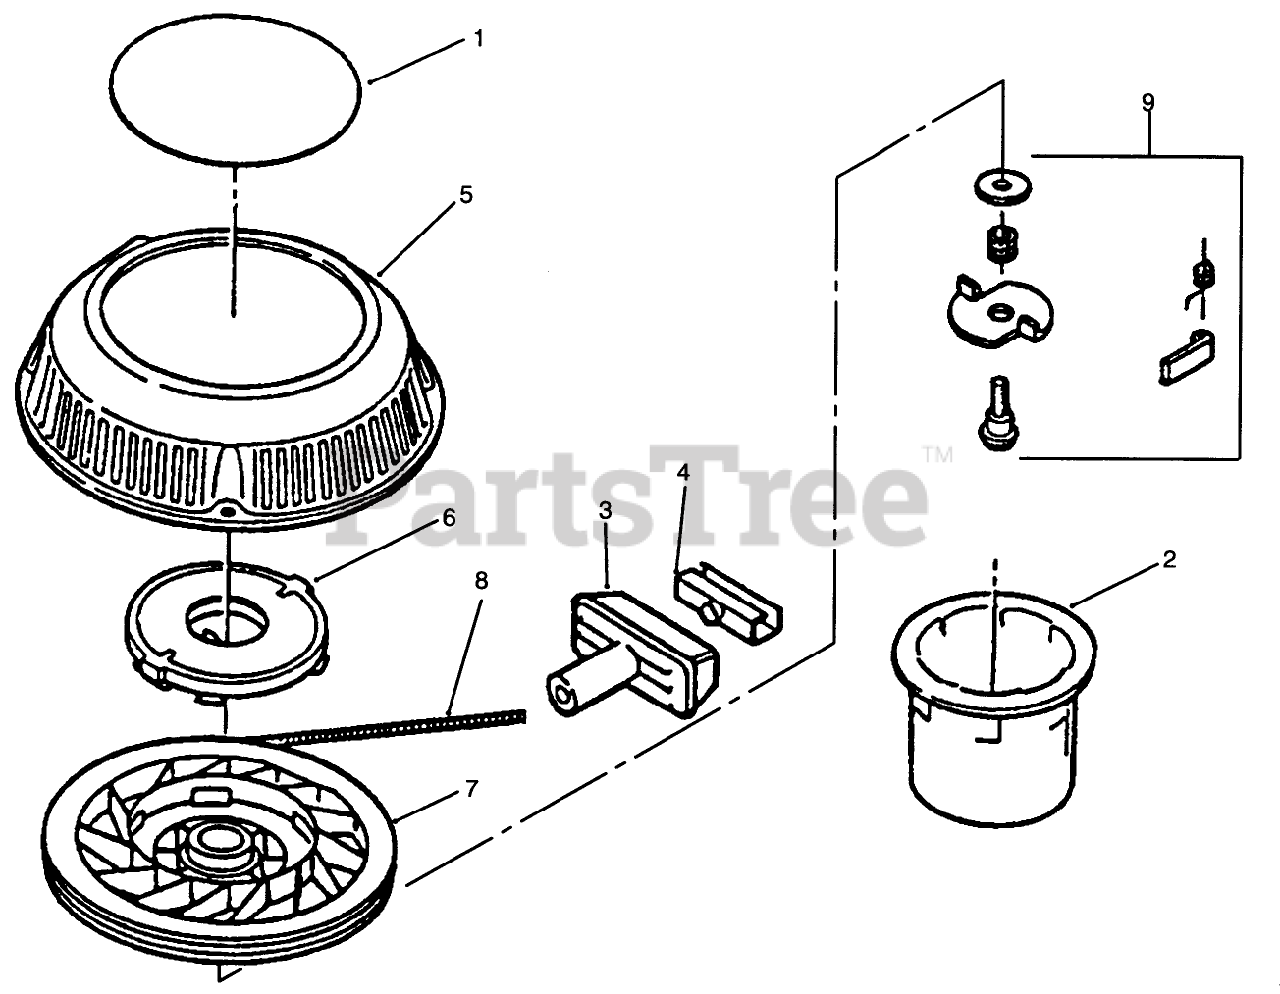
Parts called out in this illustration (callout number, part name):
2	HUB STARTER SM
4	CLIP-STARTER
5	STARTER HOUSING & SHAFT
9	DOG KIT
